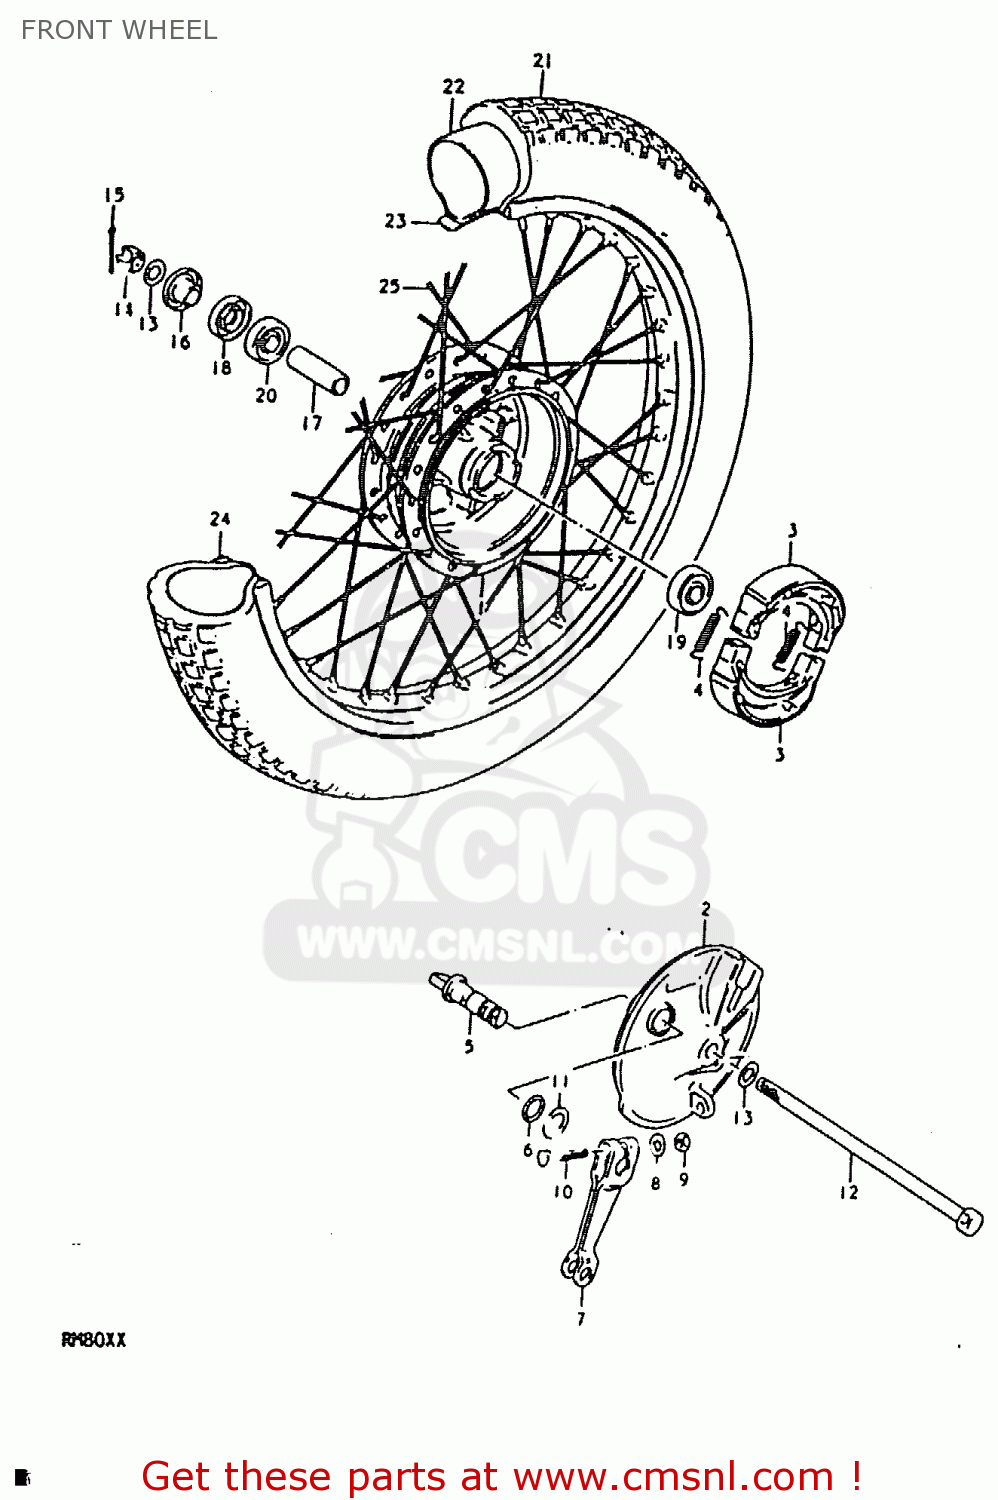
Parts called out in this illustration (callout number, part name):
1	HUB,FRONT
2	PANEL,FR BRAKE ANCHOR
3	SHOE,BRAKE (MCA)
4	SPRING(L:34)
5	CAM,FRONT BRAKE
6	O-RING (D:2.4 ID:13.8)
7	LEVER,FR BRAKE CAM
8	WASHER
9	NUT
10	BOLT(6X33)
11	WASHER (14.5X22X1.6)
12	AXLE,FRONT
13	WASHER
14	NUT
15	PIN 20X20
16	SPACER,FRONT AXLE,RIGHT
17	SPACER (10.2X16X51)
18	SEAL,OIL(15X31X5)
19	BEARING
20	BEARING
21	TIRE,FRONT
22	TUBE,INNER
23	PROTECTOR,WHEEL,INNER
24	RIM,FRONT WHEEL (1.40X17)(
25	SPOKE SET,FRONT
